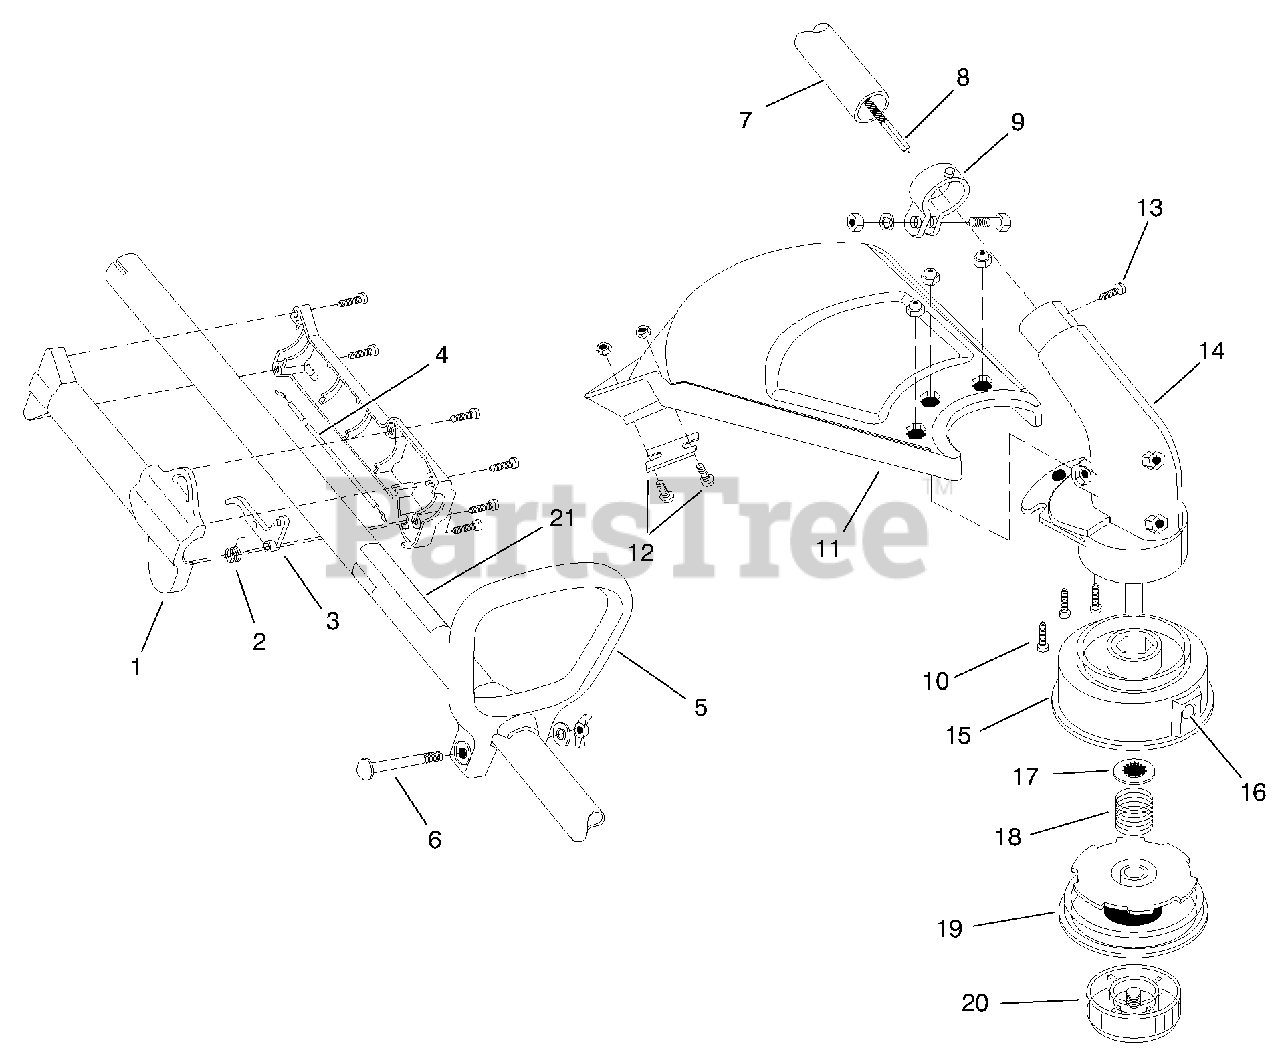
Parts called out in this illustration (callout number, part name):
1	Throttle Housing & Trigger ASM
2	Spring-Throttle Trigger
3	Throttle Trigger
4	Throttle Cable Housing ASM
5	D-Handle
6	D-Handle Hardware ASM
7	Housing-Drive Shaft
8	Flexible Drive Shaft
9	Lower Clamp ASM
10	Screw-Shield Mounting ASM
11	Shield & Blade ASM
12	Blade ASM
13	Screw-Anti Rotation
14	Gearbox ASM
15	Outer Spool & Eyelet
17	Retainer
19	Inner Reel
20	Bump Knob ASM
21	Decal-Safety Symbols
